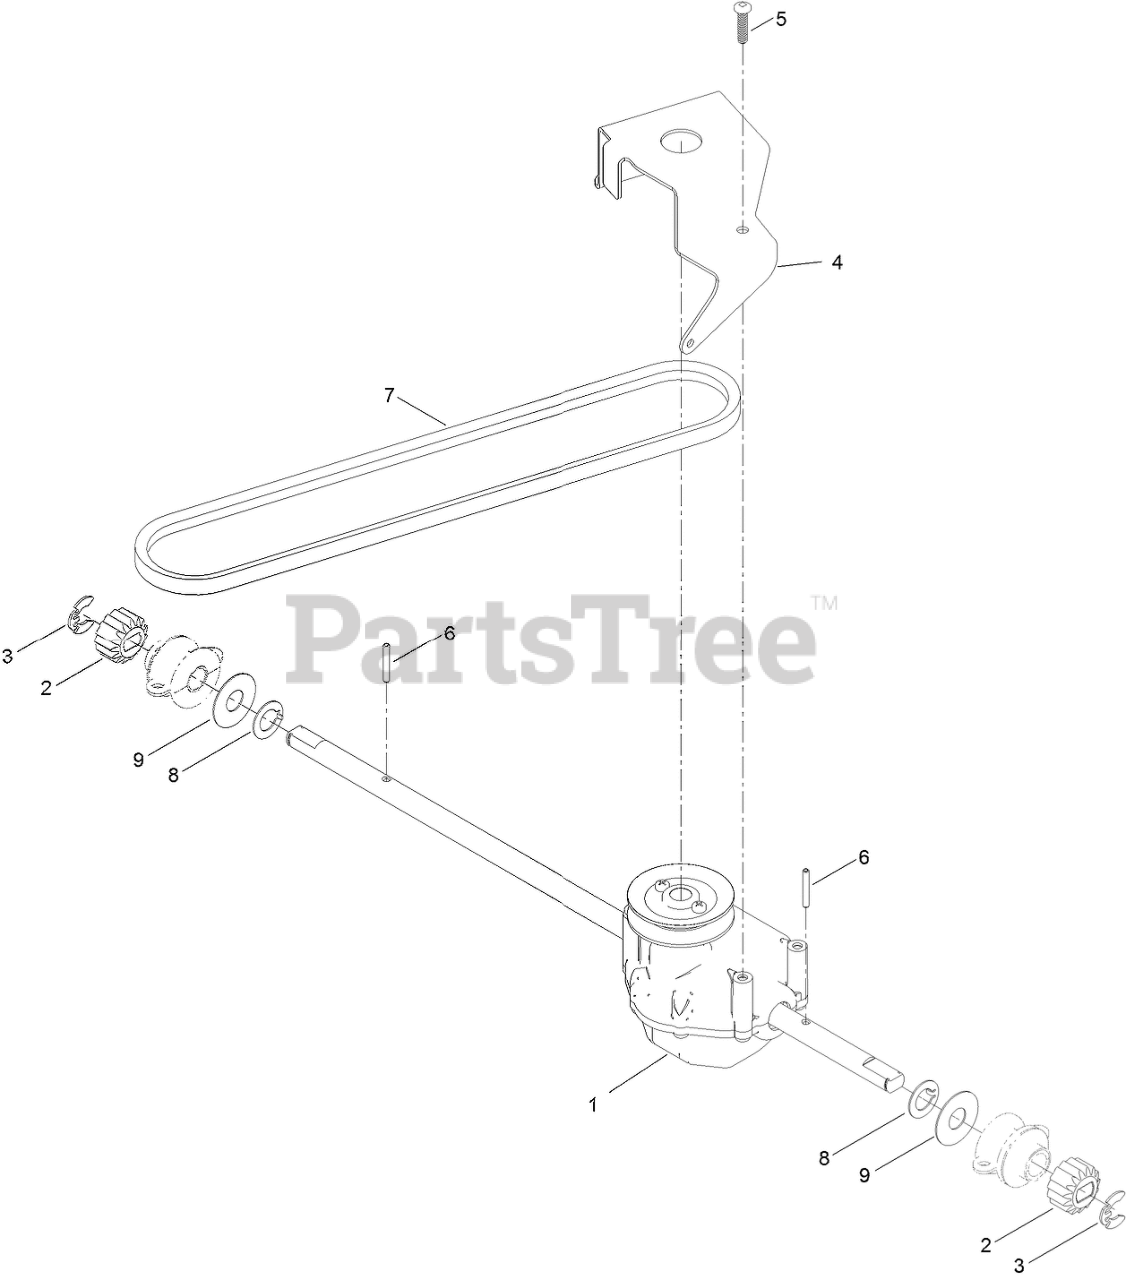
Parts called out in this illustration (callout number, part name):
1	TRANSMISSION-GEARBOX
2	GEAR-PINION, 15T
3	RING-RETAINING,CLIP
4	BRACKET-TRANSMISSION
5	SCREW-PLASTITE
6	PIN-ROLL
7	V-BELT
8	WASHER-THRUST, KEYED
9	WASHER-PLAIN
